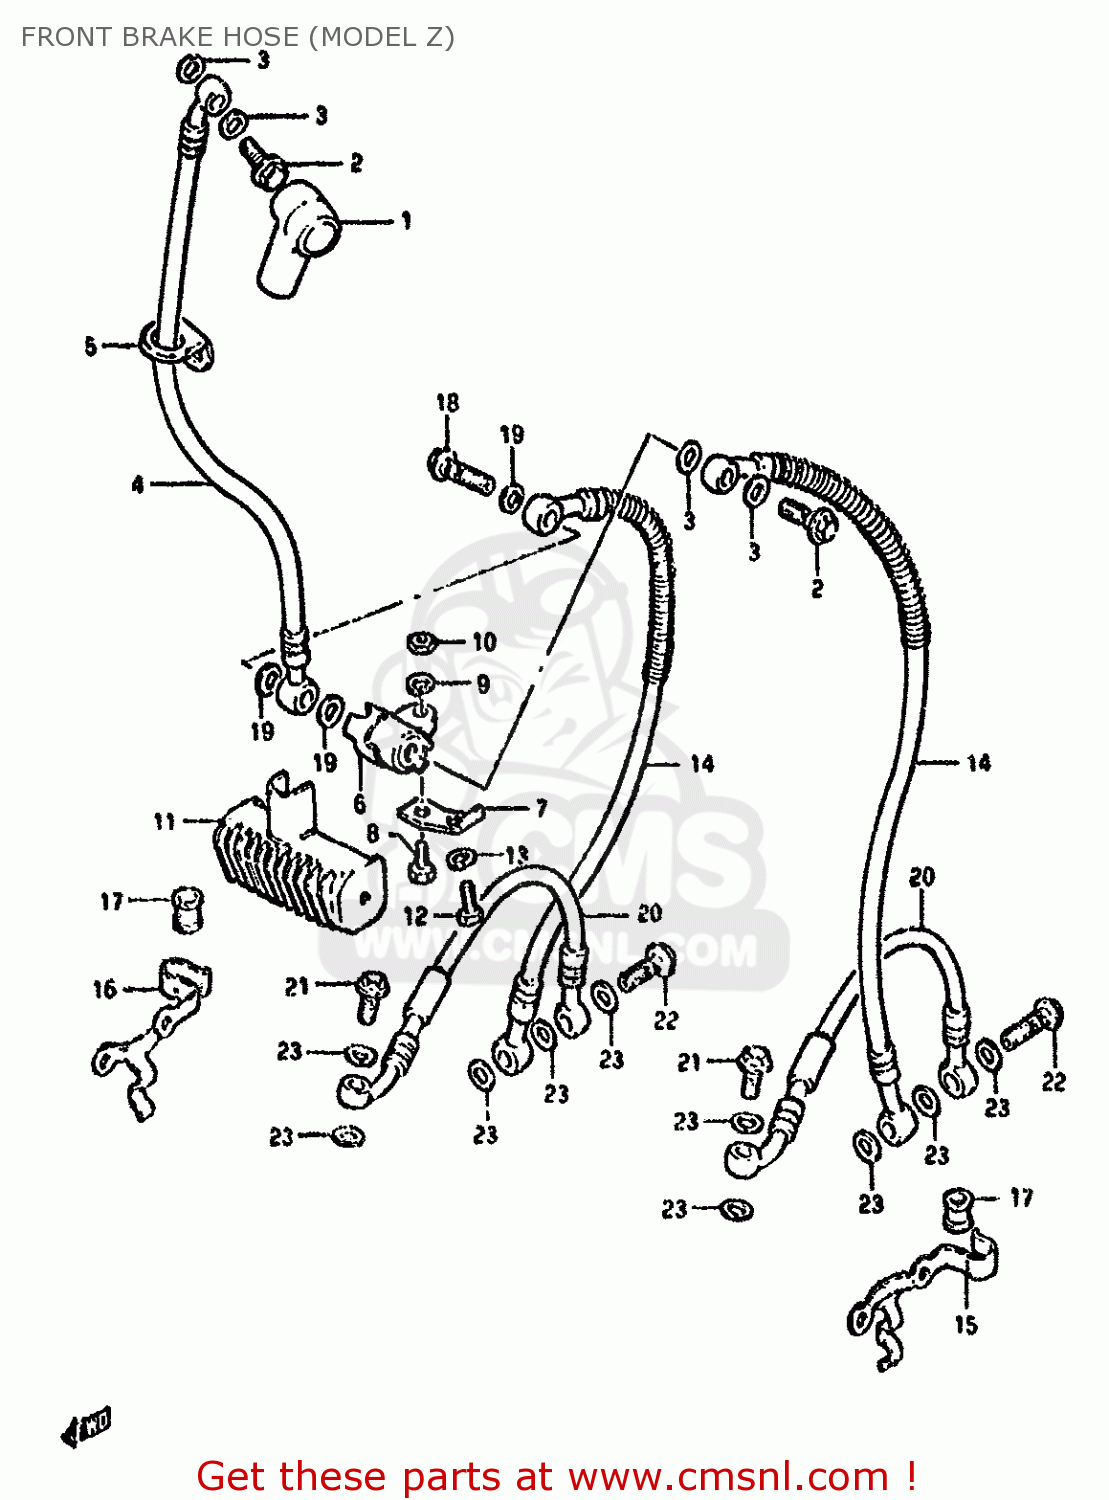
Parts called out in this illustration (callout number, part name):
1	BOOT,MASTER CYLINDER
2	BOLT,UNION
3	WASHER
4	HOSE, BRAKE NO.1 (FLAT HANDLEBAR)
5	GUIDE,BRAKE HOSE NO.1
6	JOINT,BRAKE HOSE
7	BRACKET
8	BOLT
9	LOCK WASHER
10	NUT
11	COVER,BRAKE HOSE JOINT
12	BOLT
13	LOCK WASHER
14	HOSE,FRONT BRAKE
15	CLAMP,FRONT BRAKE HOSE
16	CLAMP,FRONT BRAKE HOSE
17	BUSH,BRAKE HOSE GUIDE,NO.2
18	BOLT,UNION
19	WASHER
20	HOSE,ANTINOSE
21	BOLT,UNION
22	BOLT,UNION
23	WASHER
